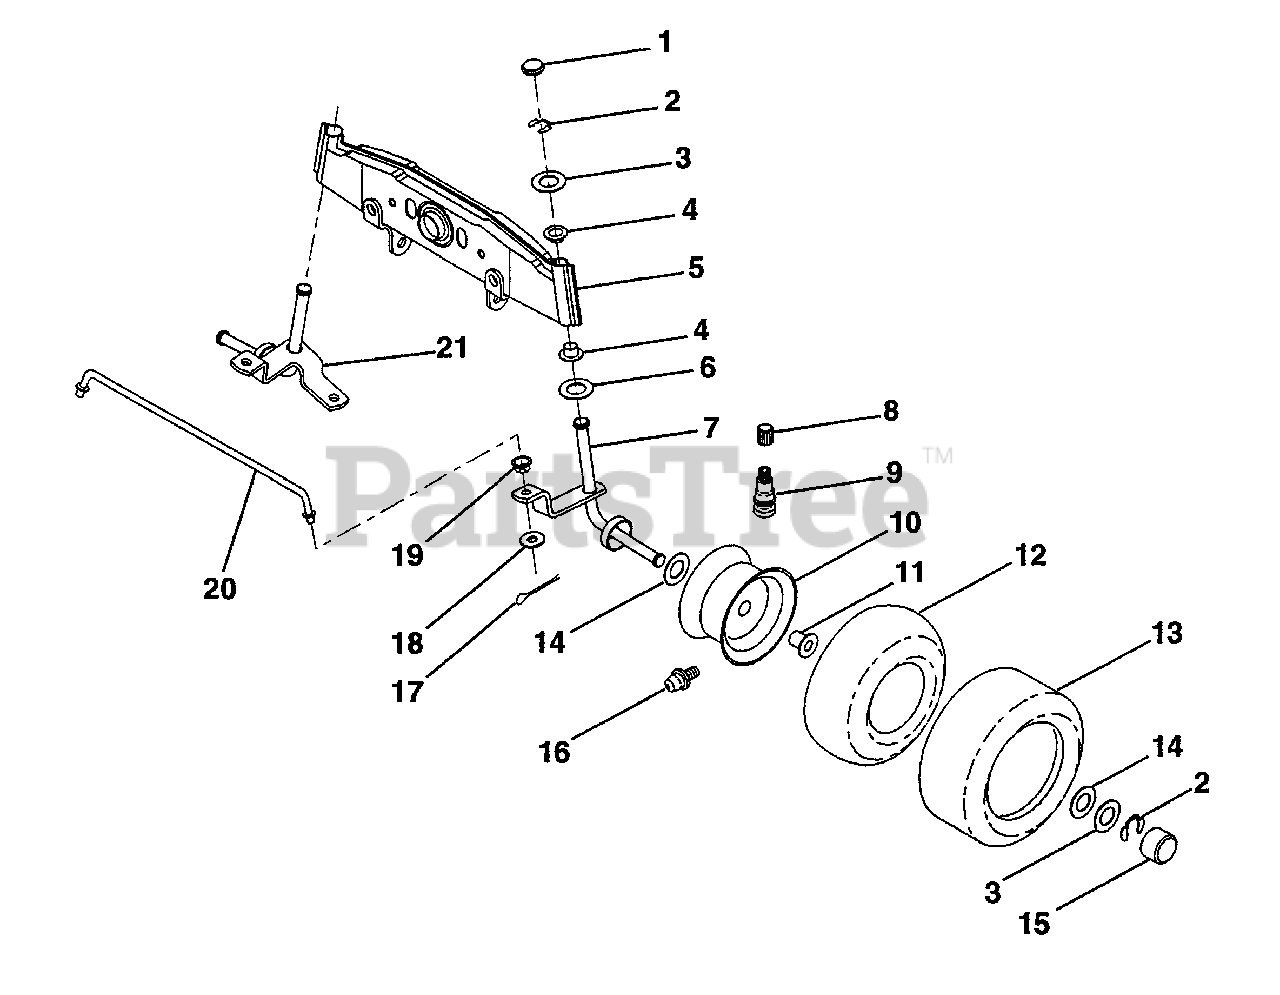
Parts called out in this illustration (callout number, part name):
1	Cap, Spindle
2	Ring, Clip
3	Washer 25/32 x 1-5/8 x 16 Ga.
5	Axle, Front
6	Bearing, Thrust
7	Spindle, R.H. Asm.
8	Cap, Valve
9	Stem, Valve
10	Rim
11	Bearing, Flange
13	Tire, Front
14	Washer 25/32 x 1-1/4 x 16 Ga.
16	Fitting, Grease
17	Pin, Cotter 1/8 x 3/4
18	Washer 13/32 x 13/16 x 16 Ga.
21	Spindle, L.H. Asm.
